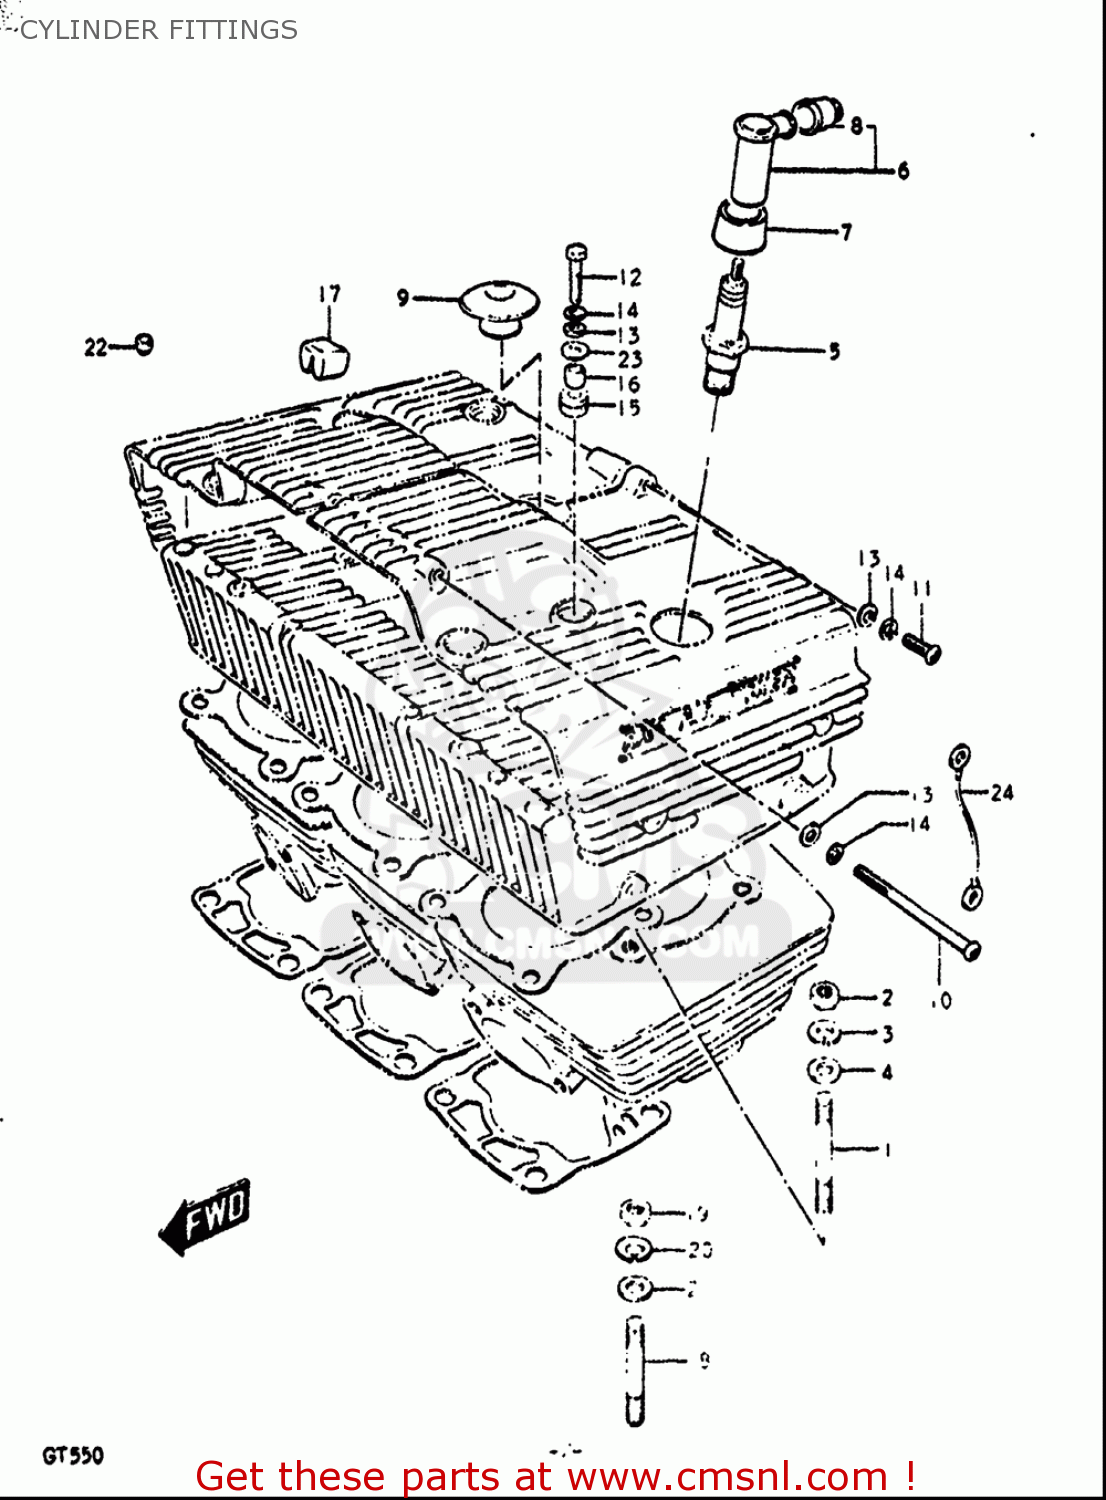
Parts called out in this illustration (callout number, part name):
1	BOLT,STUD
2	NUT
3	WASHER,LOCK
4	WASHER
5	SPARK PLUG B7ES
6	CAP,SPARK PLUG
7	SEAL,SPARK PLUG
8	SEAL,HIGH TENSION CORD
10	SCREW
11	SCREW
12	BOLT
13	WASHER
14	WASHER,LOCK
15	CUSHION
16	SPACER(6.1X8X12)
18	BOLT
19	NUT
20	WASHER,LOCK
21	WASHER
23	WASHER(6.5X14X1.6)
24	LEAD WIRE
